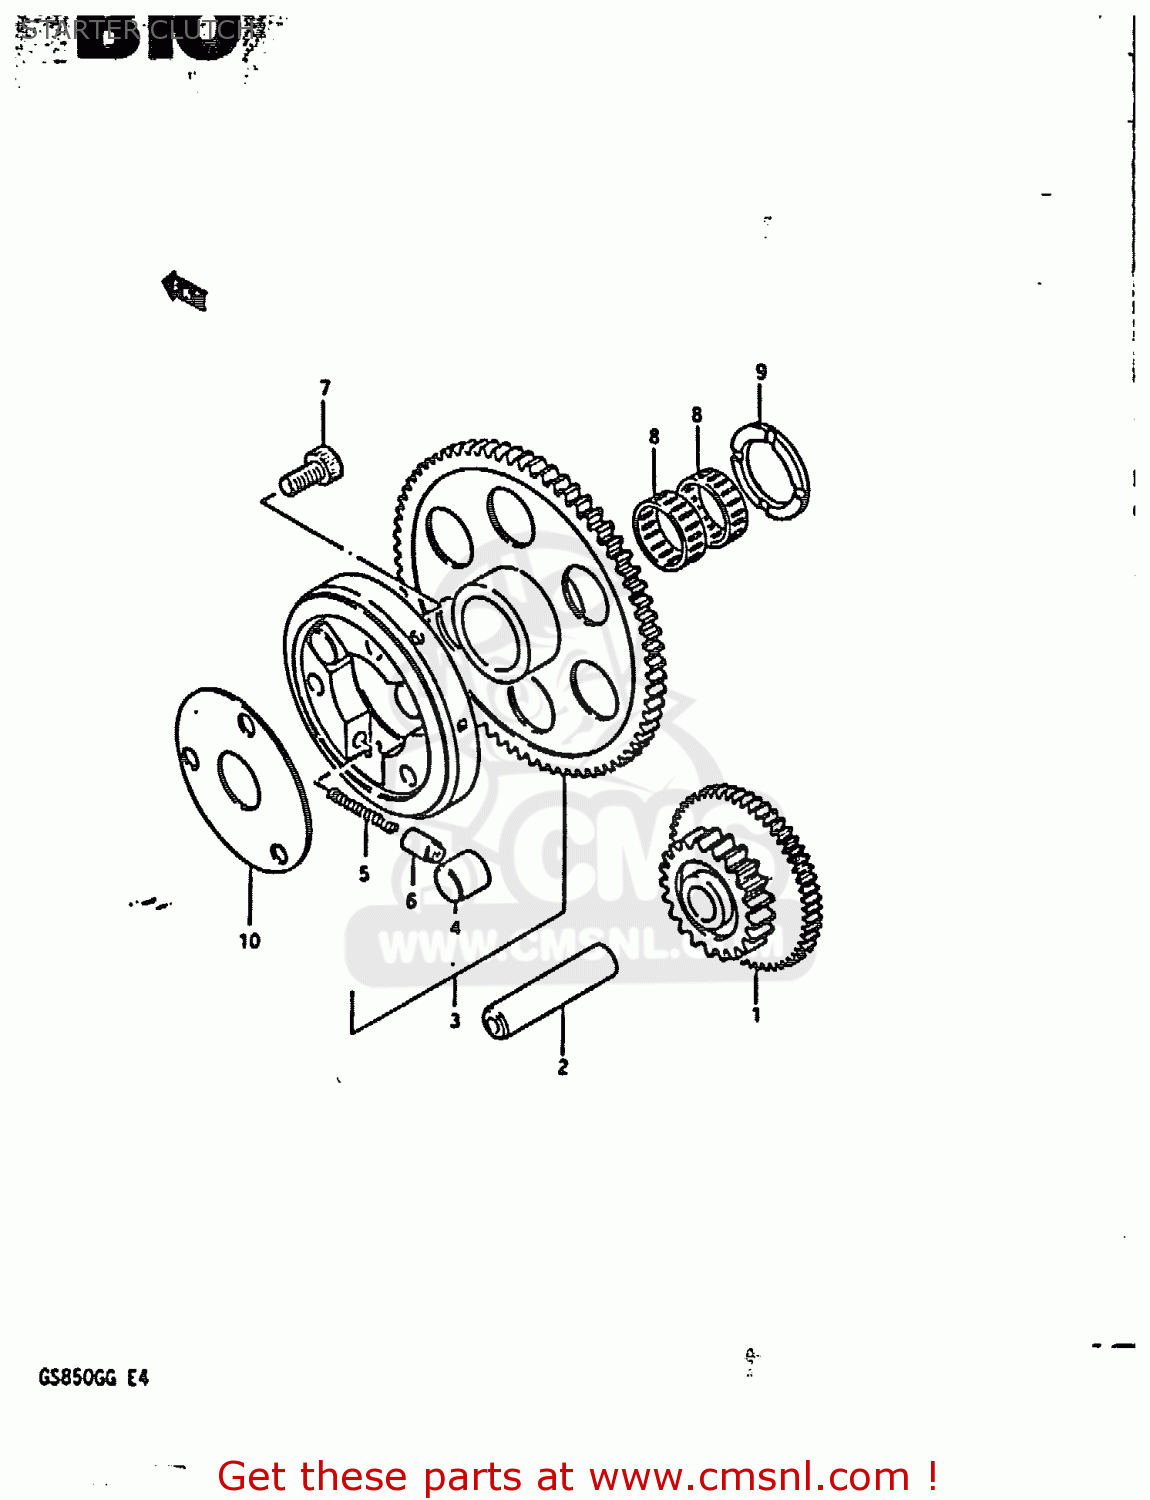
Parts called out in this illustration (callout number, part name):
1	GEAR,STARTER IDLE
2	PIN(7.4X13X61)
3	CLUTCH SET,STARTER
4	ROLLER(15X13)
5	SPRING
6	PIECE,PUSH
7	BOLT
8	BEARING(25X29X9.9)
9	WASHER(25X38X2.5)
10	SHIM,STARTER CLUTCH HUB
